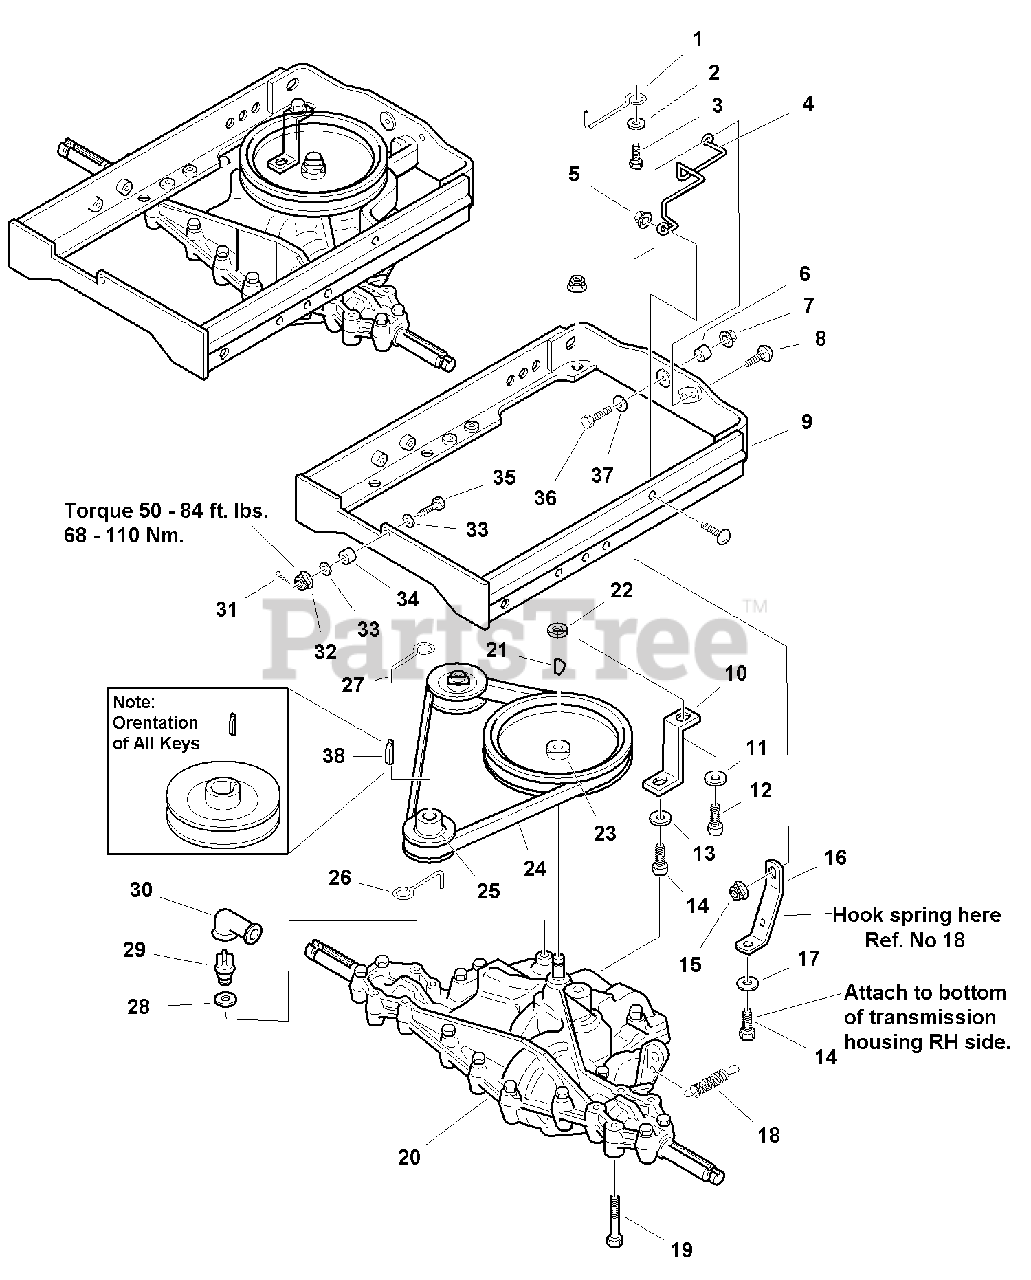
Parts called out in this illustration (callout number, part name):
1	BELT STOP
2	WASHER, 13/32 x 1 x 1/8
3	CAPSCREW, Hex Head, 3/8-16 x 1-3/4
4	GUIDE, Belt, Transmission
5	NUT, Hex, Flange Lock, 5/16-18
7	NUT, Hex, Flange Lock, 1/2 x 13
8	CARRIAGE BOLT, 5/16-18 x 5/8
9	CARRIER ASSEMBLY
10	STRAP, Torque
11	WASHER, 5/16
12	CAPSCREW, Hex, Whizlock, 5/16-18 x 3/4
13	WASHER, 7/16
14	CAPSCREW, Hex Head, Taptite, 3/8-18 x 1-1/4
15	NUT, Hex, Flange, Whizlock, 5/16-18
16	STRAP, Torque
17	WASHER, Plain, 13/32 x 7/8 x 5/64
18	SPRING, Return
19	CAPSCREW, Hex Head, 5/16-18 x 2-1/4
21	KEY, Woodruff, #9
22	RING, Retaining
23	PULLEY ASSEMBLY, Driven, Transmission
25	PULLEY ASSEMBLY, Drive, Engine
30	COVER, Terminal
31	PIN, Cotter 1/8 x 1-1/2
32	NUT, Hex Head, 1/2 x 20
33	WASHER, Belleville 1/2
35	CAPSCREW, Hex Head, With Hole, 1/2-20 x 1-3/4
36	CAPSCREW, Hex Head, 1/2-13 x 1-1/4
37	WASHER
38	KEY, Hi-Pro
